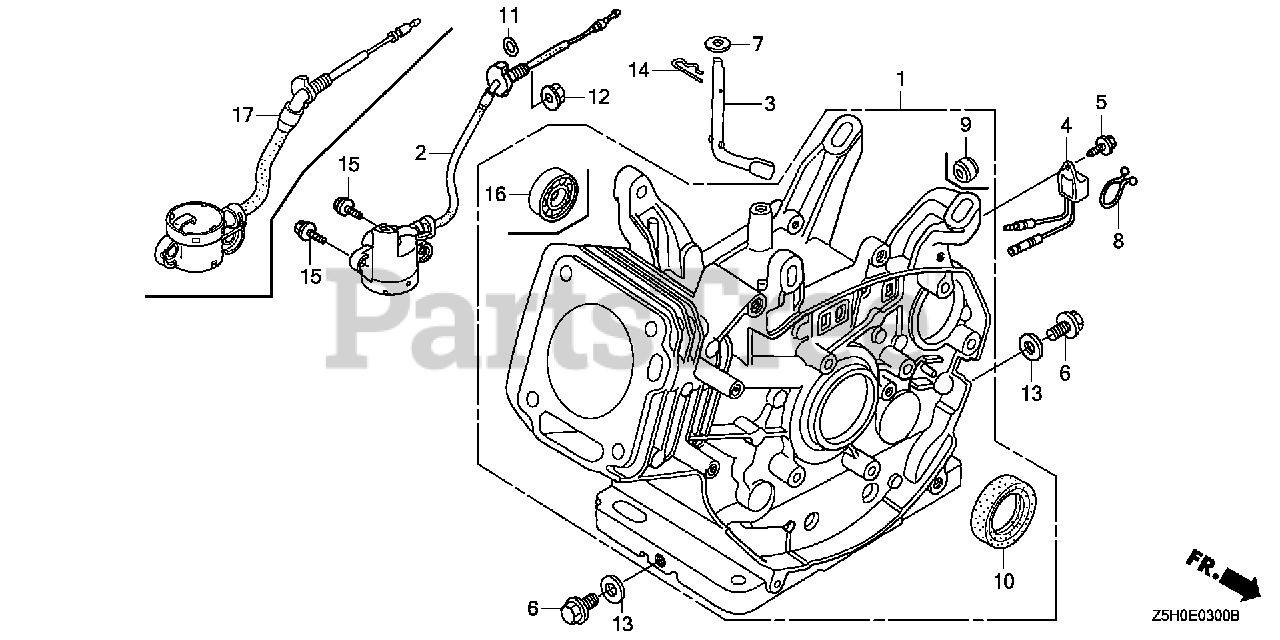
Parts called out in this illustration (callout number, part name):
1	CYLINDER ASSY. (SELF STARTER)
3	SHAFT, GOVERNOR ARM
6	BOLT, DRAIN PLUG (12X15)
7	WASHER (8.2X17X0.8)
9	PLUG, SEALING (RUBBER 10MM)
10	OIL SEAL (30X46X8)
13	WASHER, DRAIN PLUG (12MM)
14	PIN, LOCK (10MM)
